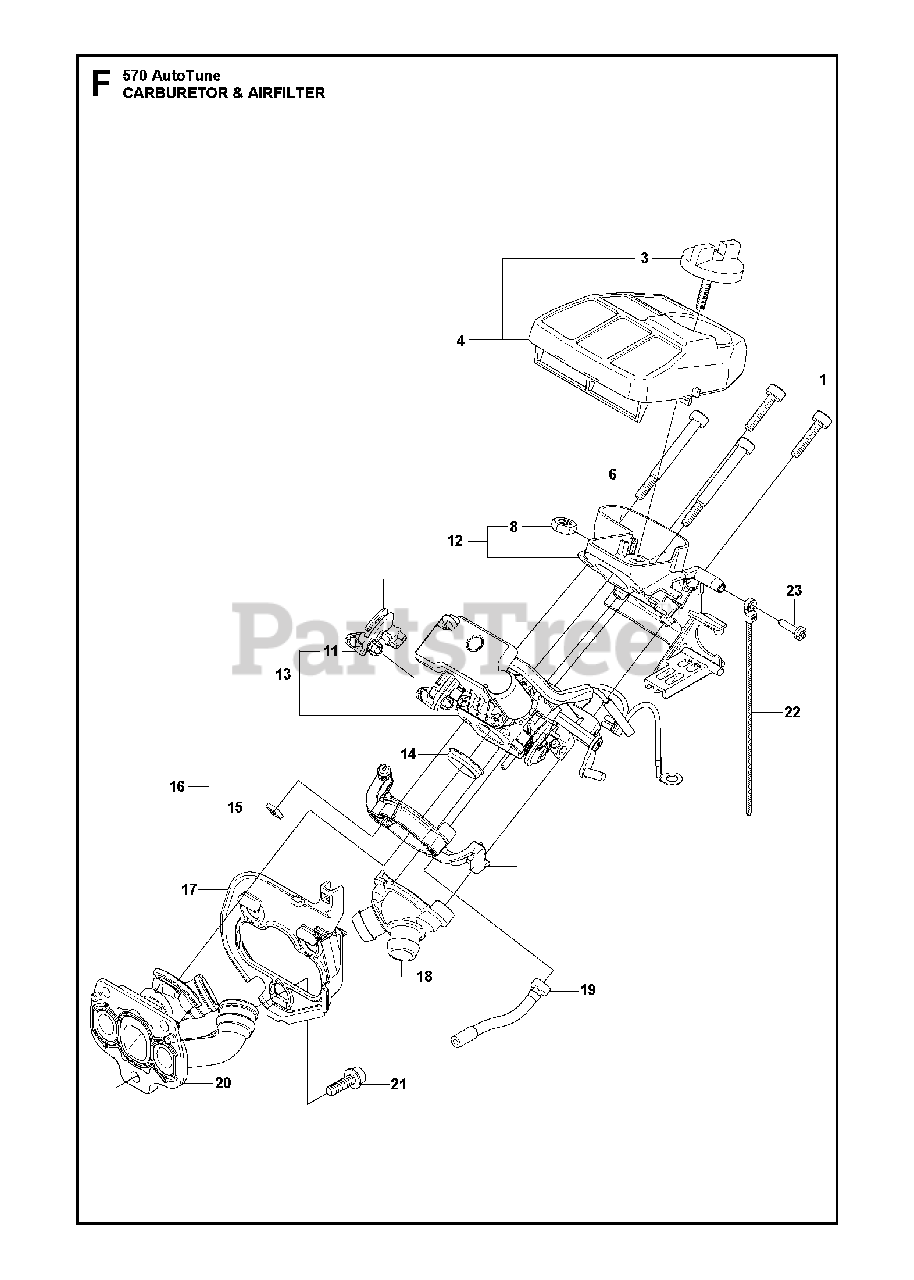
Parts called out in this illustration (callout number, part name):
3	KNOB
4	RP AIR FILTER
4	AIR FILTER
6	SCREW 4X46
8	NUT
11	THROTTLE LEVER ASSY
12	FILTER HOLDER
13	CARBURETTOR C1M-EL40H
15	NUT
